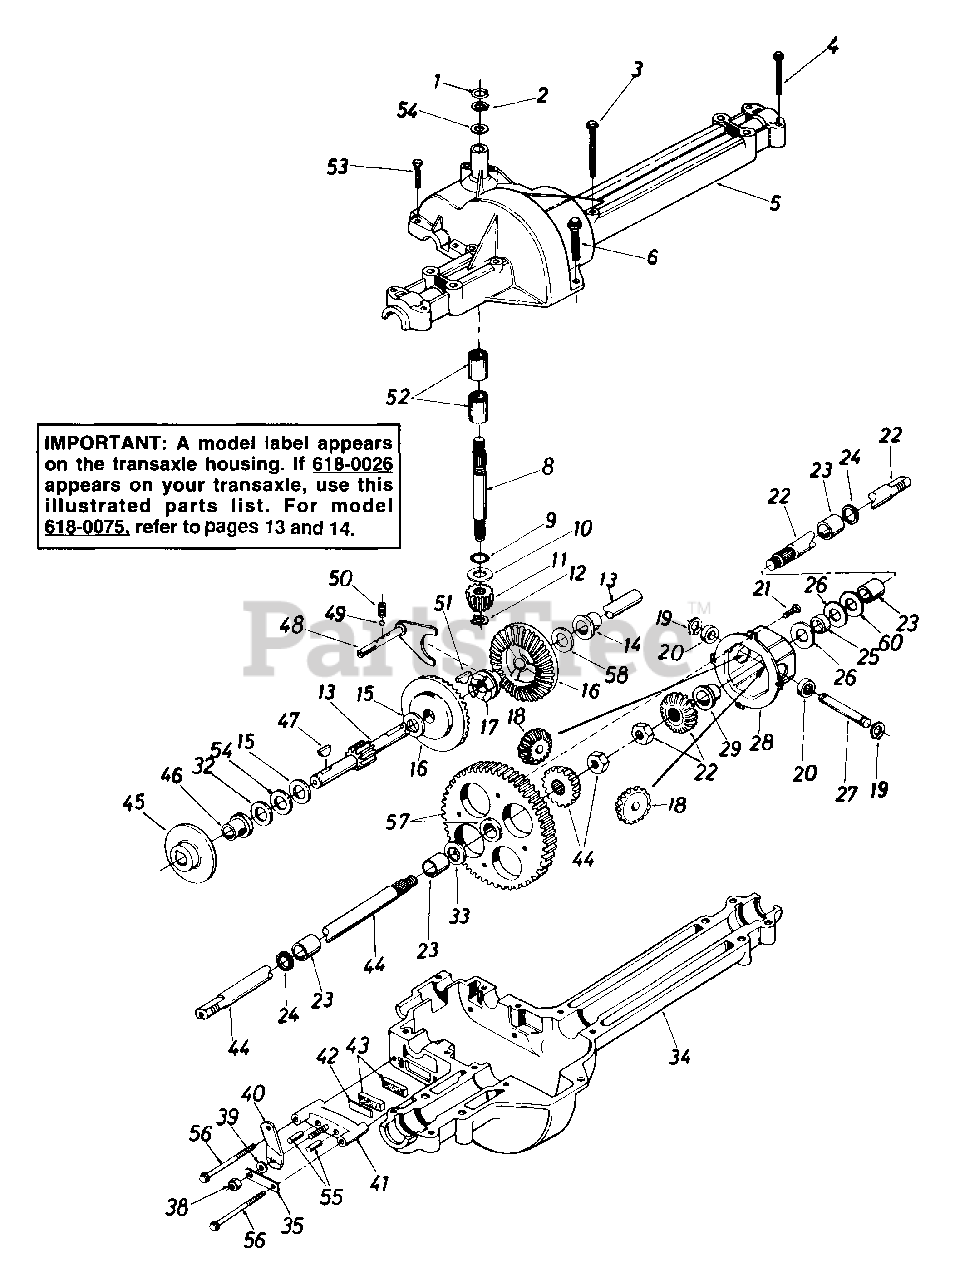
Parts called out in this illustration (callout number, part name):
1	Wire Ring
2	Retaining - Ring
3	Hex Bolt 1/4-20 x 1.75" Lg.
4	Hex Tap Scr. 1/4-20 x 1.25" Lg.
5	Upper Housing
6	Hex TT-Tap Scr. 1/4-20 x .75" Lg.
8	Input Shaft
9	Square Seal 5/8" I.D.
10	Thrust Washer 5/8" I.D. x 1.25" O.D.
11	Pinion Input 14T
12	Retaining Ring
13	Drive Shaft
14	Flange Brg. 5/8" I.D. x 3/4" Lg.
15	Fl-Wash. 5/8" I.D. x 1.25"
16	Bevel Gear 42T
17	Clutch Collar
18	Miter Gear 15T (H.D.)
19	Snap Ring
20	Thrust Bearing
21	Pan Head Scr. 1/4-20 x .50" Lg. w/Patch
22	Axle R.H. Ass'y.
23	Sleeve Bearing 3/4" I.D. x 1.0" Lg.
24	Oil Seal 3/4" I.D.
25	Axle Spacer
26	Fl-Wash. .760" I.D. x 1.5" O.D.
27	Cross Shaft
28	Differential Can Ass'y.
32	Washer
33	Fl-Wash. .760" I.D. x 1.5" O.D.
34	Lower Housing
35	Anti-Rotation Brkt.
38	Hex Nut 5/16-24 Thd.
39	Fl-Wash. .344" I.D. x .875" O.D.
40	Actuating Arm
41	Brake Yoke
42	Puck Plate
43	Brake Puck
44	Axle L.H. Ass'y.
45	Brake Disc
46	Flange Bearing 5/8" I.D. x 15/16" Lg.
47	Woodruff Key 3/16 x 5/8 HT
48	Shift Fork Ass'y.
49	Ball Detent .250" Dia.
50	Spring Detent
51	#9 Hi-Pro Key 3/16" x 3/4" Dia. HT
52	Needle Brg. 5/8" I.D. x 1/2" Lg.
53	Hex Bolt 1/4-20 x 1.00" Lg.
54	Fl-Wash. 5/8" I.D. x 1" O.D. x .020 Thk.
55	Actuating Pin 5/16" Dia.
56	Hex Wash Hd. Self-Tap Scr. 1/4-20 Thd.
57	Differential Gear 72T Ass'y. w/Bearing
58	Fl-Wash. 5/8" I.D. x 1" O.D. x .020 Thk.
60	Washer
